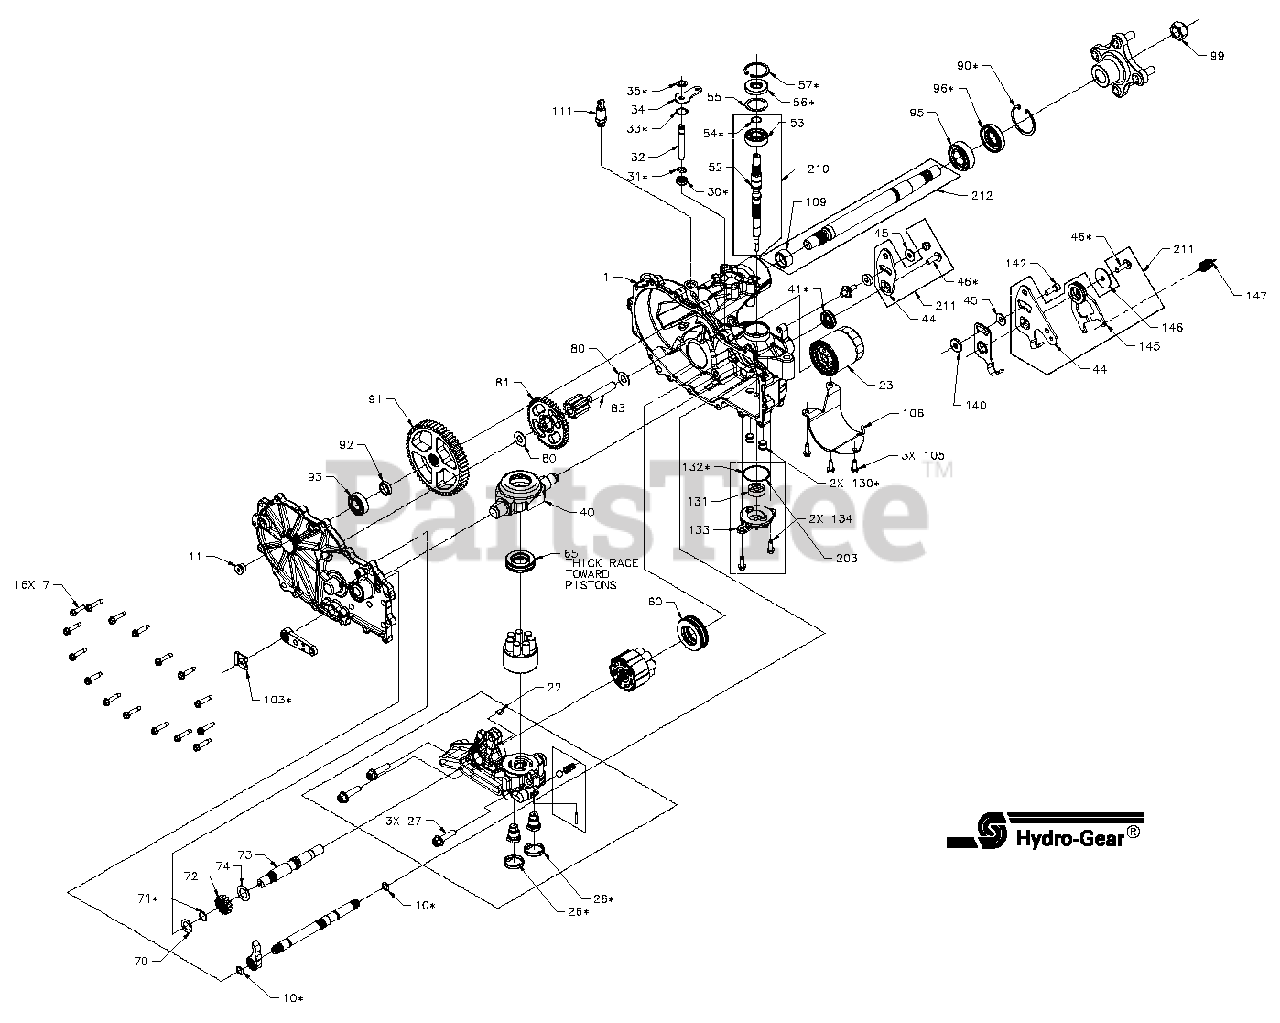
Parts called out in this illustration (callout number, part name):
7	HFHCS 1/4-20 x 1.25
11	Plug, 9/16-18 (Metal)
22	Plate, Bypass
30	Seal, Lip .375 x .75 x .25
31	Ring, Retention .375 External
33	Ring, Retention .750 Internal
35	Ring, Retention .375 Ext
40	Trunnion, Swashplate
45	Washer, .34 x .88 x .06
46	TWHCS 5/16-24 x 1.00
53	Bearing, Ball 17 x 40 x 12 Open 6203
55	Washer, 1.23 x 1.56 x .04
56	Seal, Lip 17 x 40 x 7
57	Ring, Ret 1.59 Int
65	Bearing, Thrust Ball 30 x 52 x 13
70	Washer, .63 x 1.0 x .05
71	Ring, Retaining .625
74	Washer, .72 x 1.16 x .04
80	Washer, .5 x 1.0 x .03
83	Jack Shaft
90	Ring, Ret 2.06 Int
95	Bearing, Ball 1.0 x 52 x 15 Open 6205M
96	Seal, Lip 25 x 52 x 10 TC (Gray)
99	Nut, Hex Lock 3/4-16
105	HFHCS 1/4-20 x .75
131	Assembly, Gerotor Tang x 1.15 x .39
134	HFHCS 1/4-20 x .75
142	SHCS 5/16-24 x 1 Patch
146	Washer, .343 x 1.5 x .062
NS	Sealant
